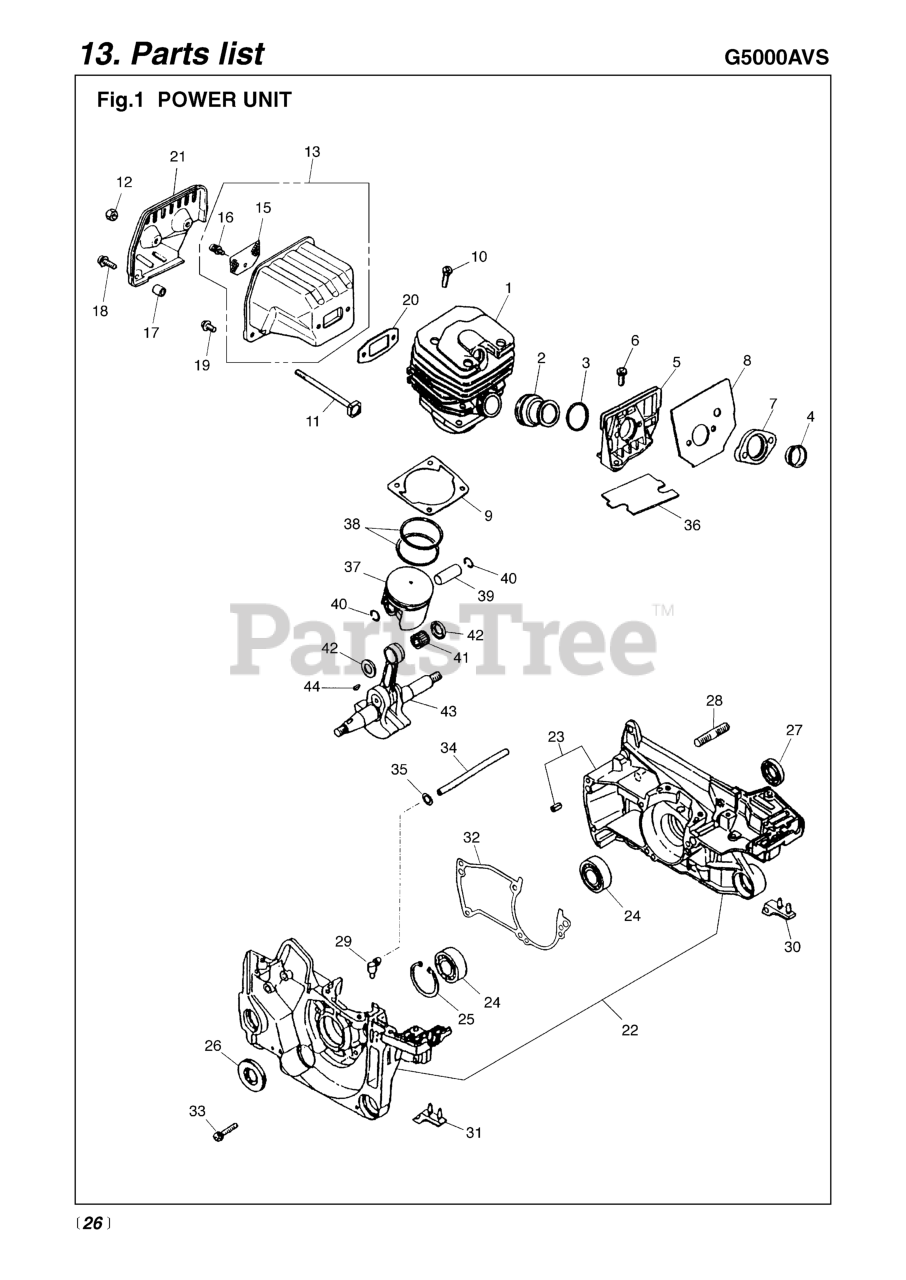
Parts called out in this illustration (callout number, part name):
1	CYLINDER
2	PIPE
3	SPRING
4	GUIDE
6	SCREW (REPLACES 2616-24320)
8	GASKET (RPLS 2880-14360)
9	GASKET, CYLINDER (RPLS -14210)
10	BOLT (RPLS 2850-14220)
11	BOLT
12	NUT, MUFFLER (RPLS 3356-15230
13	MUFFLER ASSY (RPLS -15102)
15	ARRESTER, SPARK
19	SCREW
20	GASKET
21	COVER
22	CRANKCASE ASSY
24	BEARING (REPLACES 2810-21240)
25	RING, SNAP, M35 X 1.5
26	SEAL, OIL
27	SEAL, OIL
28	BOLT
30	STOPPER, REAR (RPLS 2670-22510
31	STOPPER, REAR
32	GASKET (REPLACES 2670-21311)
36	MAT (RPLS 2810-22410)
37	PISTON
38	PISTON RING
39	PIN, PISTON
40	RING, SNAP
41	BEARING
42	WASHER, THRUST
43	CRANKSHAFT COMPLETE
44	KEY
